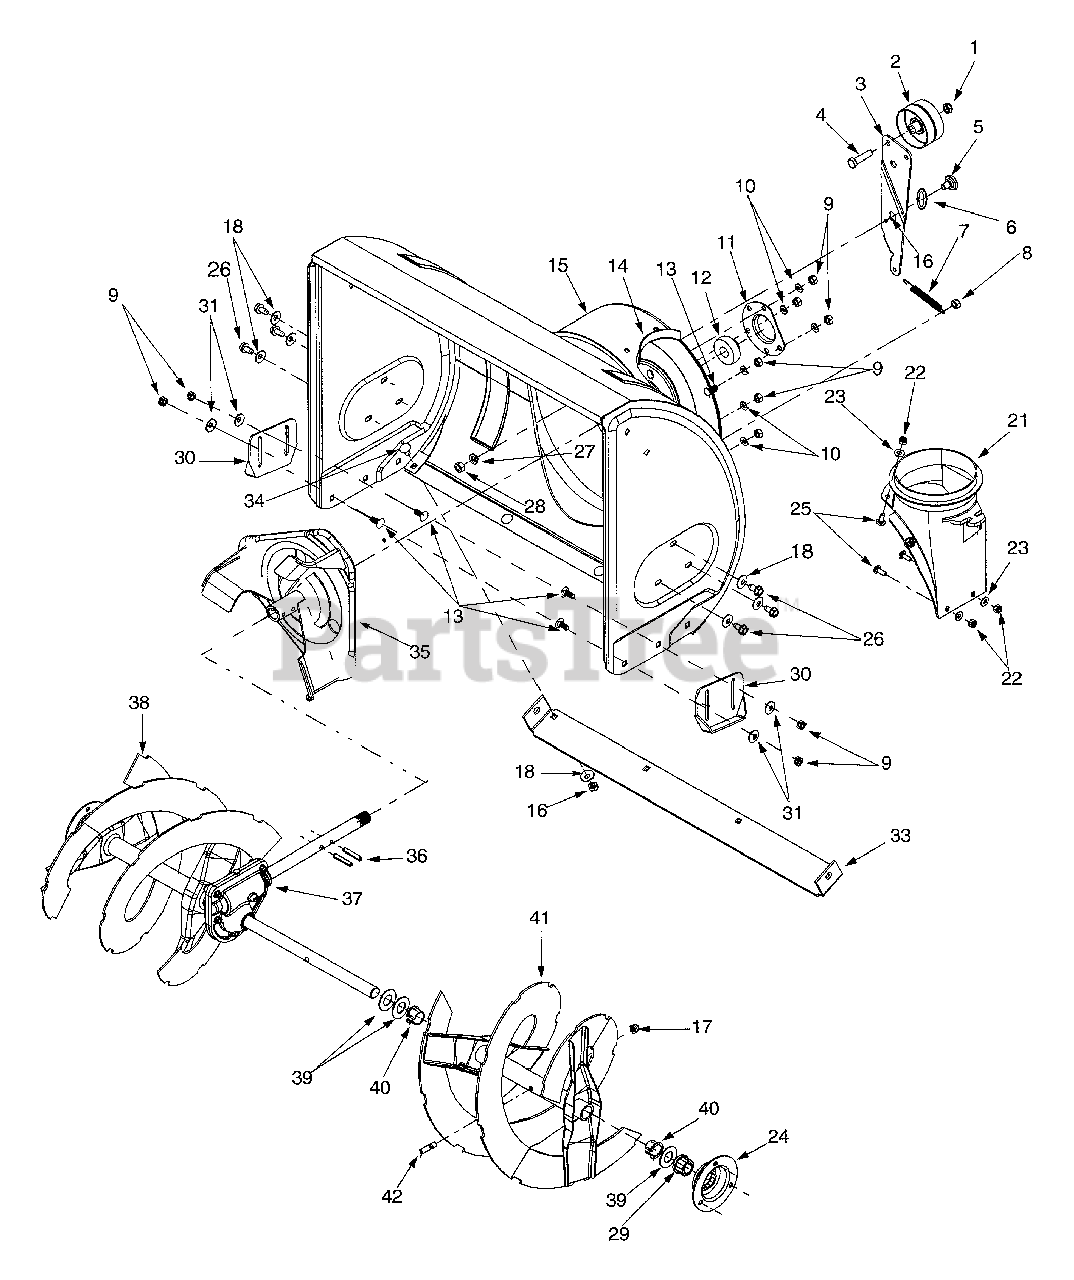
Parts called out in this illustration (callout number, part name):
1	Lock Jam Nut 3/8-24
2	Flat Idler
4	Hex Cap Screw 3/8-24 x 1.50
5	Shoulder Screw
6	Flat Washer
7	Extension Spring
8	Hex Nut 5/16-18
9	Hex Nut 5/16-18
10	Lock Washer 5/16
11	Housing
12	Ball Bearing
13	Carriage Bolt 5/16-18 x .75
17	Lock Nut 5/16-18
18	Bell Washer
21	Flat Washer
23	Carriage Screw 1/4-20 x .75
24	Hex Washer Screw 5/16-18
25	Lock Washer 3/8
26	Hex Nut 3/8-16
27	Hex Flange Bearing
29	Bell Washer
34	Carriage Bolt 5/16-18 x .62
37	28" Gear Assembly
39	Flat Washer
40	Flange Bushing
42	Shear Bolt 5/16-18 x 1.5
